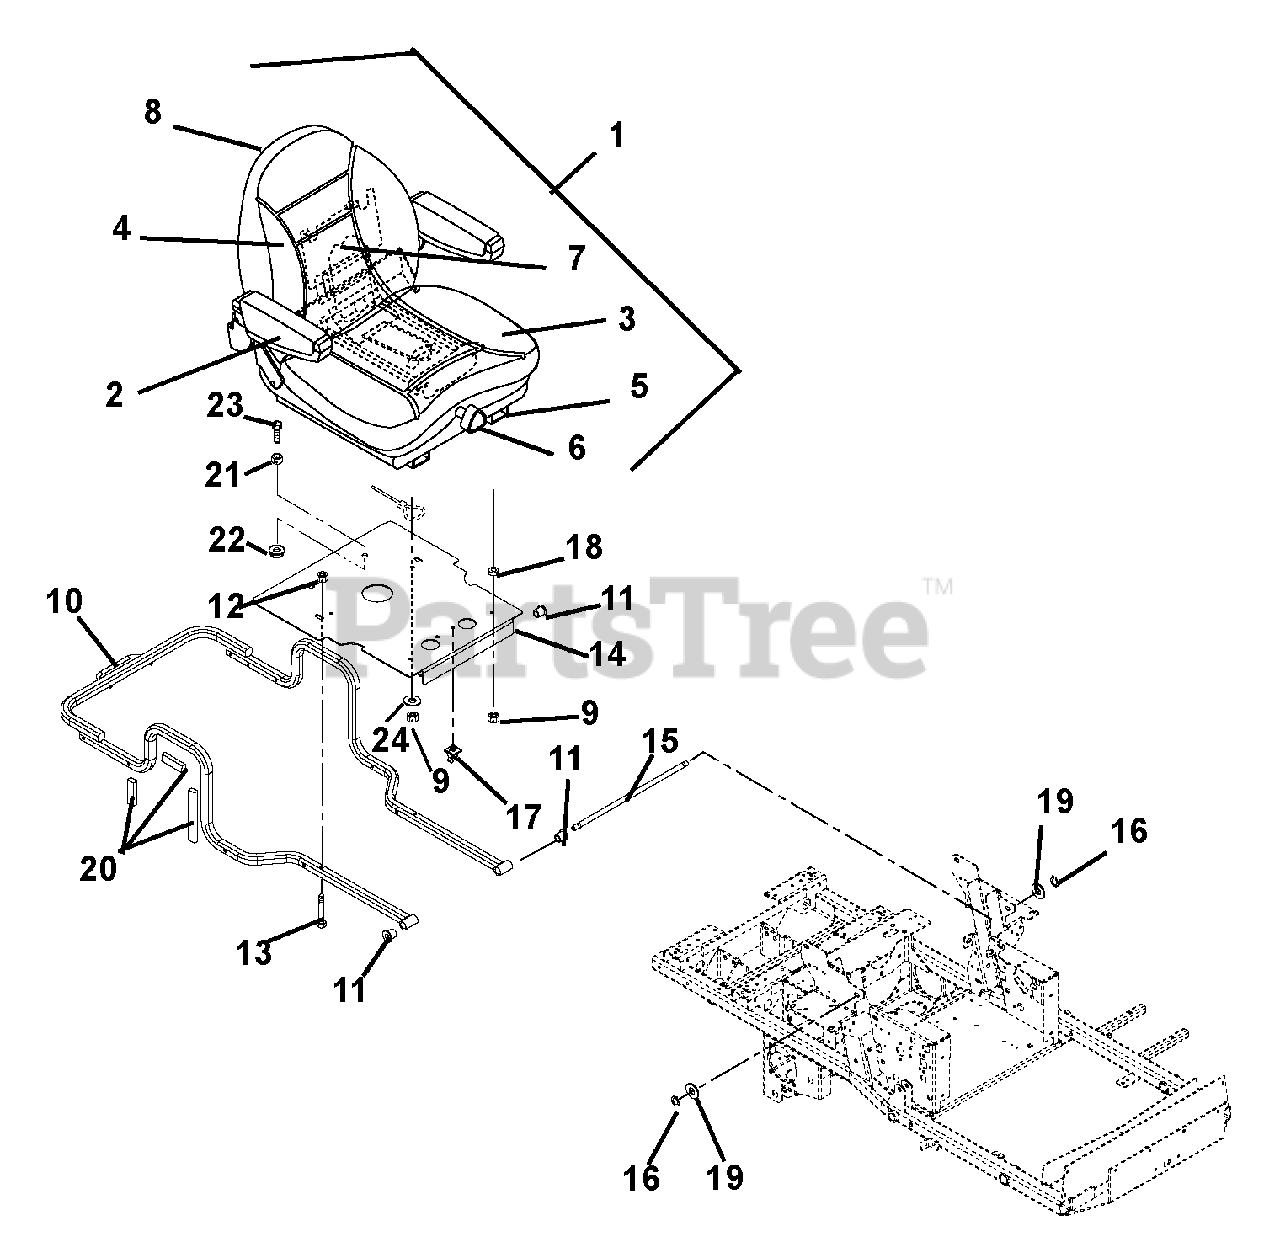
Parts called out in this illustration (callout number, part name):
1	Seat, Suspension, Light Gray
2	Kit, Arm Pad (1 per bag)
3	Kit, Seat Cushion, Light Gray
4	Kit, Back Cushion, Light Gray
5	Kit, Seat Slide
6	Kit, Seat Knob
7	Kit, Spring and Saddle
8	Kit, Seat Back Panel
9	Nut, Locking Top Flange .31-18
10	Weldment, Hood Frame
11	Bushing, Flange .515 x .750 x .745 x 1.00
12	Nut, Locking Top Flange .38-16
13	Bolt, Rib Neck .38-16 x 1.50
14	Weldment, Seat Pivot Mount
15	Rod, Seat Frame Pivot
16	Ring, Retaining External .500 x .050
18	Bushing, Sleeve .377 x .624 x .235
19	Washer, Flat Steel .531 x 1.06 x .095
20	Tape, VHB
21	Nut, Hex .50-13
22	Nut, Locking Top Flange .50-13
23	Bolt, Hex .50-13 x 1.50
24	Washer, Flat Steel .344 x 1.125 x .135
